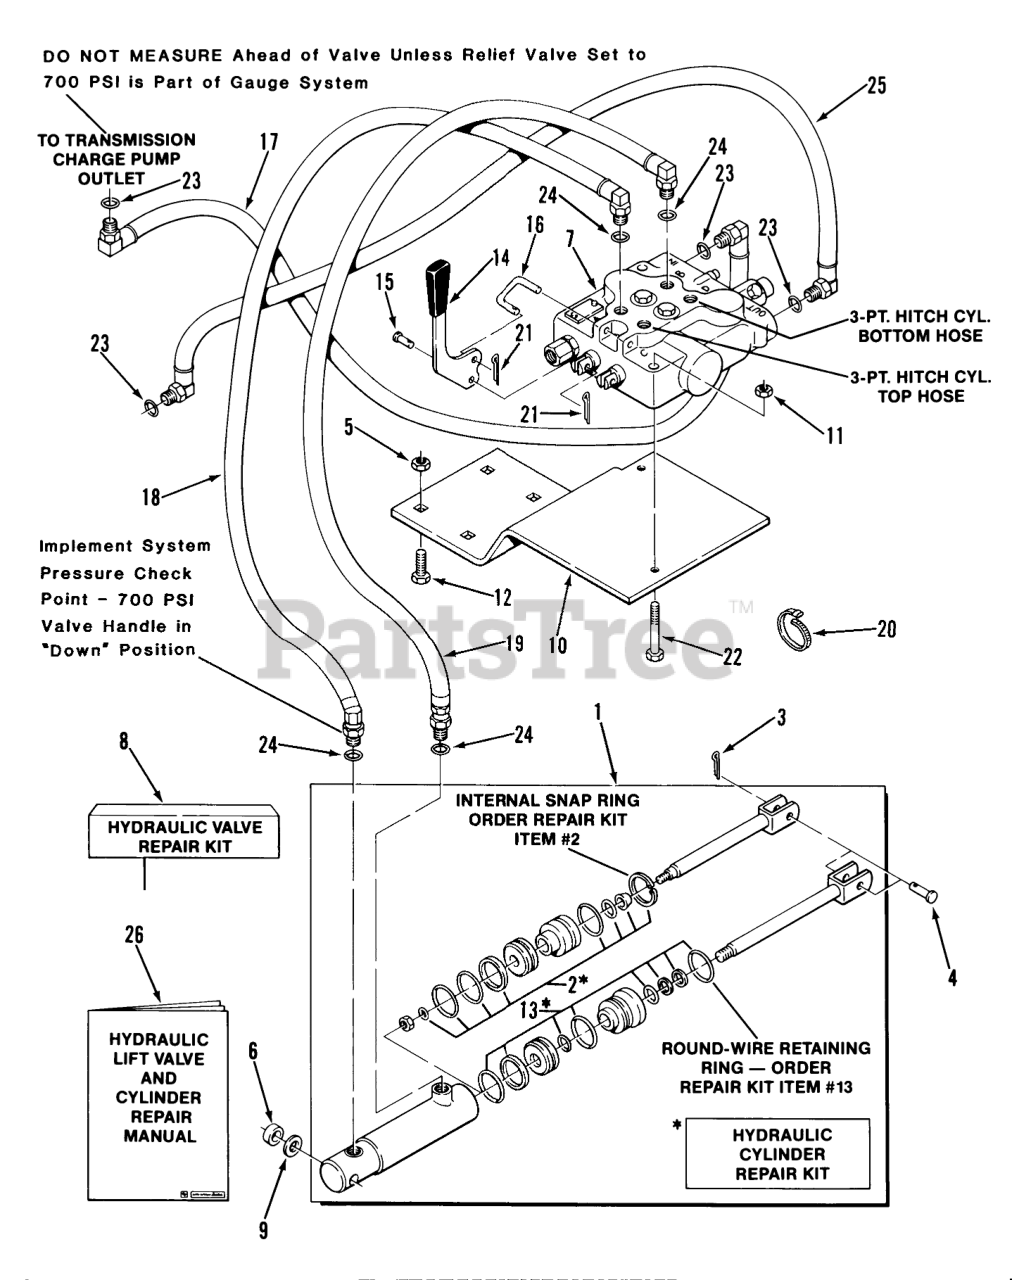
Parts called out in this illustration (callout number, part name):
1	CYLINDER
2	S/A O-RING&GASKET AS
4	CLEVIS PIN
5	Nut
6	Spacer
7	Hydraulic Valve
8	S.A. Valve Repair Kit
9	WASHER
10	Mounting Bracket
11	Nut
12	Bolt
13	S/A 108872 HYD CYL
14	VALVE HANDLE
15	Pin
16	C-HOOK
17	ASSY HYD HOSE
18	Hose-Valve Port "A" To Cylinder Front Port 37.75 in. (95.9 cm)
19	ASSY HYD HOSE
20	PLASTIC TIE
21	Cotter Pin
22	HEX HD CAP SCREW -4
23	0-Ring
24	O RING
25	Hose-Transmission Filter Adapter To Valve Outlet Port 31.5 in. (80.0 cm)
26	Repair Manual
